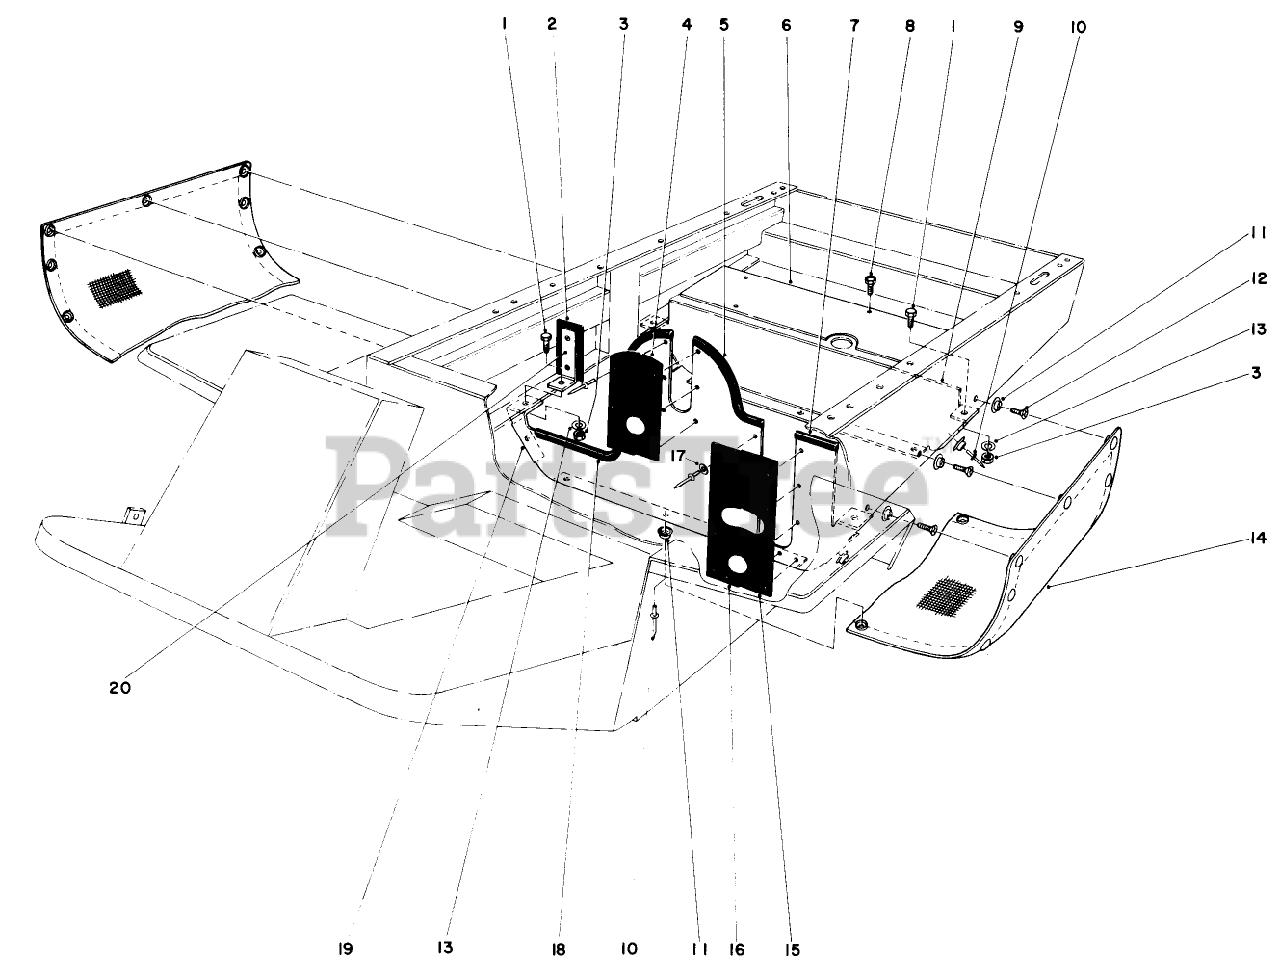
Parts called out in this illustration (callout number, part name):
1	SCREW-HH
2	Rubber Side Shield
3	NUT-HEX
4	Flap Rubber Drive Coupling
5	SEAL TRIM-GM 52 DD
6	Grass Shield-Engine
7	Seal-Rubber Extrusion
8	Screw Self Tapping
9	Shield-Rear (Incl. Ref. #10 & 11)
10	RIVET-POP
11	SNAP STUD
12	Self Tapping Screw
13	WASHER-LOCK/SP
14	GRASS SCREEN BAG
15	LH PTO RUBBER FLAP
16	Flap-Rubber P.T.O. R.H.
17	WASHER
18	Seal-Rubber Extrusion
19	Shield Front (Incl. Ref. #4-5, 7, 10-11 & 15-18)
20	Shield Side (Incl. Ref. #2 & 10 & 17)
